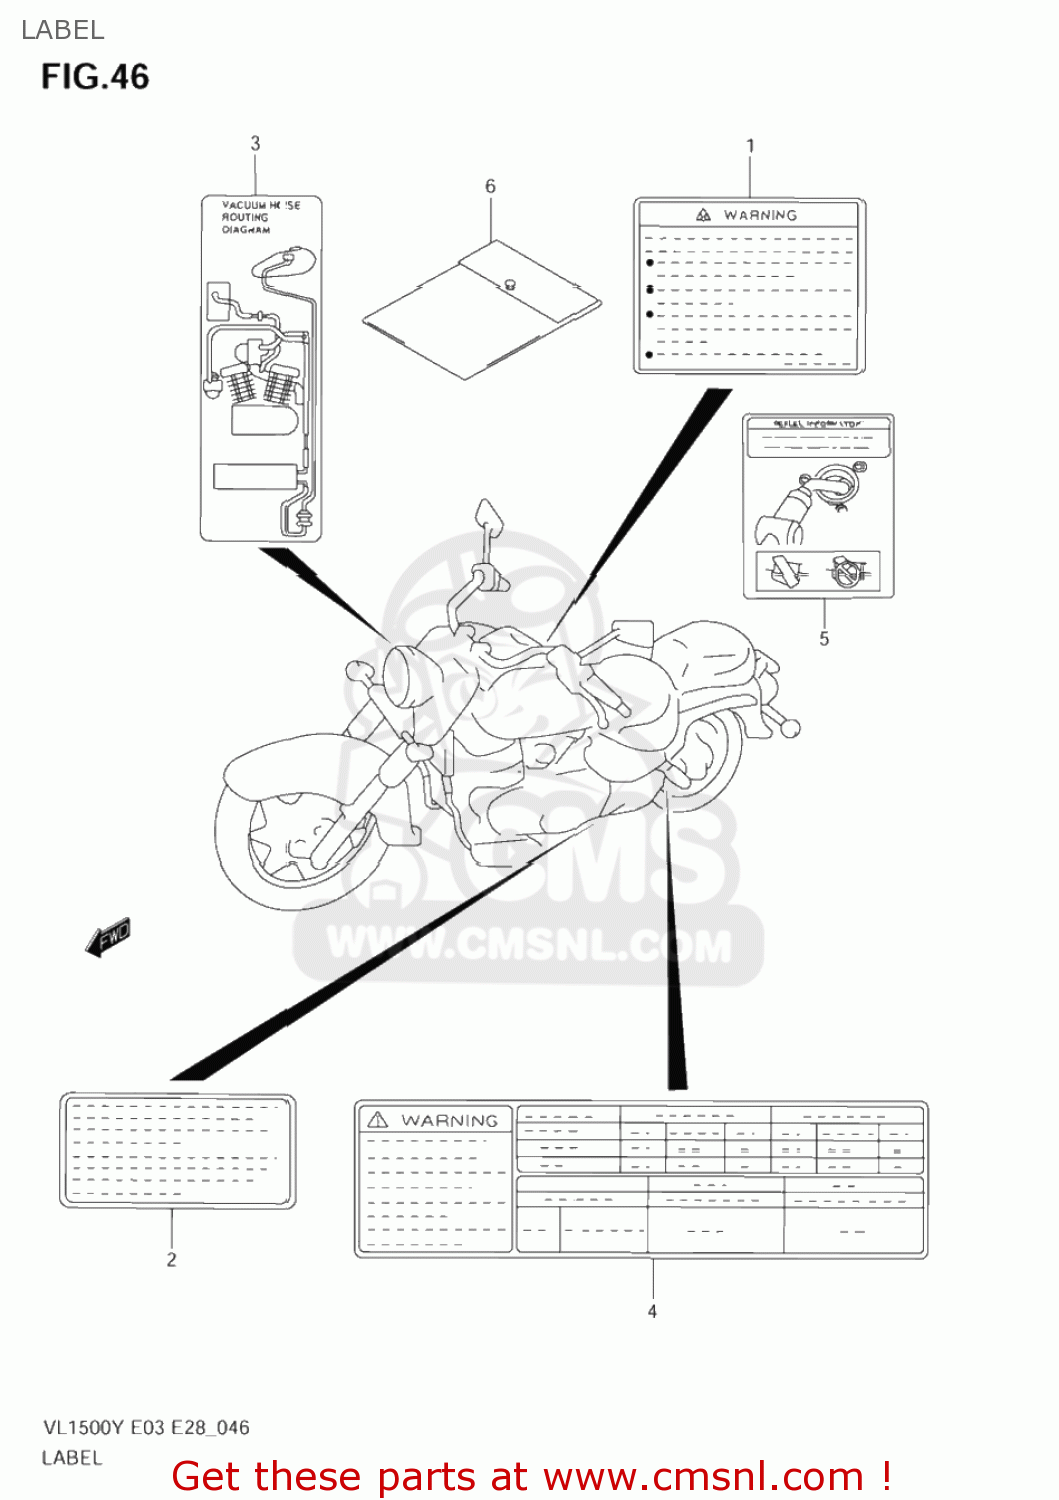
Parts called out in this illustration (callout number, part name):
1	LABEL,GENERAL WARNING
2	LABEL,MANUAL NOTICE
3	LABEL,VACUUM HOSE ROUTING
4	LABEL, TIRE INFORMATION
5	LABEL,FUEL INFORMATION
6	BAG COMP,OWNERS MANUAL
7	MANUAL,OWNER'S
